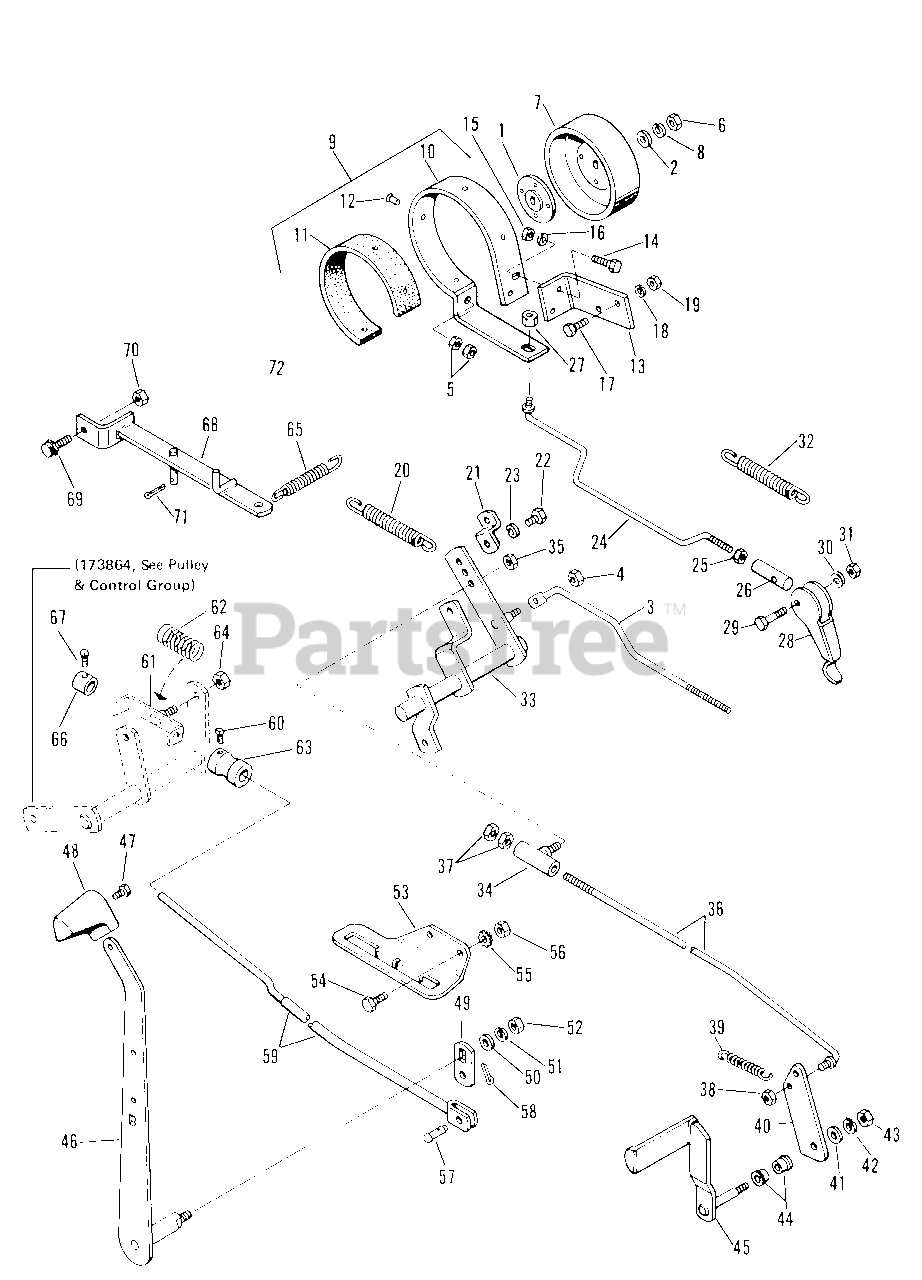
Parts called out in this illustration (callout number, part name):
1	Special Washer
2	Plain Washer, 3/8"
3	Brake Rod
4	Full Hex Nut, 5/16"-18
5	Full Hex Nut, 3/8"-16
6	Full Hex Nut, 7/16"-14
7	Brake Drum
8	Lock Washer, 7/16"
9	Brake Band & Lining Assy.
10	Brake Band
11	Brake Lining
12	Rivet No. 7 x 5/16"
13	Brake Band Bracket
14	Hex Cap Screw, 3/8"-16 x 1"
15	Full Hex Nut, 3/8"-16
16	Lock Washer, 3/8"
17	Hex Cap Screw, 1/4"-20 x 3/4"
18	Lock Washer, 1/4"
19	Full Hex Nut, 1/4"-20
21	Spring Clip
22	Hex Cap Screw, 7/16"- 14 x 1-1/4"
23	Lock Washer, 5/16"
24	Parking Brake Rod Assy.
25	Full Hex Lock Nut, 5/16"-18
27	Full Hex Nut, 5/16"-18
28	Parking Brake Lever
29	Hex Cap Screw, 1/4"-20 x 1-1/4"
30	Double Lock Washer, 1/4"
31	Full Hex Lock Nut, 1/4"-20
33	Pivot Lever Assembly
34	Guide Rod Assembly
35	Full Lock Hex Nut, 5/16"-18
36	Clutch & Brake Rod Assy.
37	Full Hex Nut, 5/16"-18
38	Full Lock Hex Nut, 5/16"-18
39	Tension Spring
40	Arm-Foot Pedal
41	Plain Washer, 3/8"
42	Lock Washer, 3/8"
43	Full Hex Nut, 3/8"-16
45	Foot Pedal Assembly
46	Variable Planetary Lever Assy.
47	Hex Self Forming Thread Screw, 1/4"-20 x 7/8"
50	Plain Washer, 3/8"
51	Lock Washer, 3/8"
52	Full Hex Nut, 3/8"-16
54	Special Screw
55	Lock Washer, Shakeproof, 5/16"
56	Nut, Twin Pilot
58	Cotter Pin, 3/32" x 3/4"
59	Rod Assembly
60	Sq. Hd. Set Screw, 1/4"-20 x 3/8" Grade 8
61	Rod Guide Assy.
63	Brake Detent
64	Full Lock Hex Nut, 3/8"-24
65	Tension Spring
66	Set Collar
67	Sq. Hd. Set Screw, 1/4"-20 x 3/8" Grade 8
68	Brake Lever Assembly
69	Brake Pad Assembly
70	Hex Jam Nut, 5/16"-18
71	Cotter Pin, 3/32" x 3/4"
